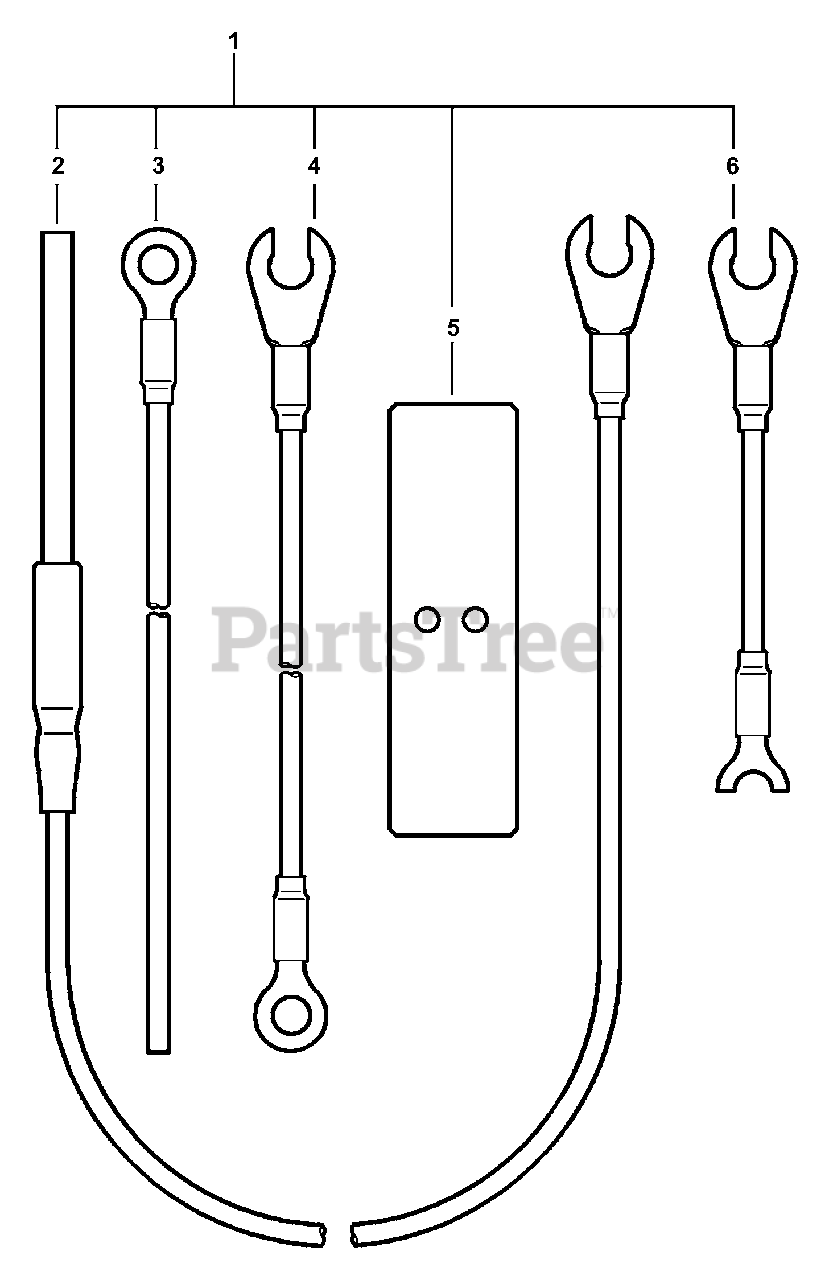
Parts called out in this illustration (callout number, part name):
1	STATIC PROTECTION KIT
3	LEAD 900 MM
4	LEAD
5	TAPE, ADHESIVE
6	LEAD
